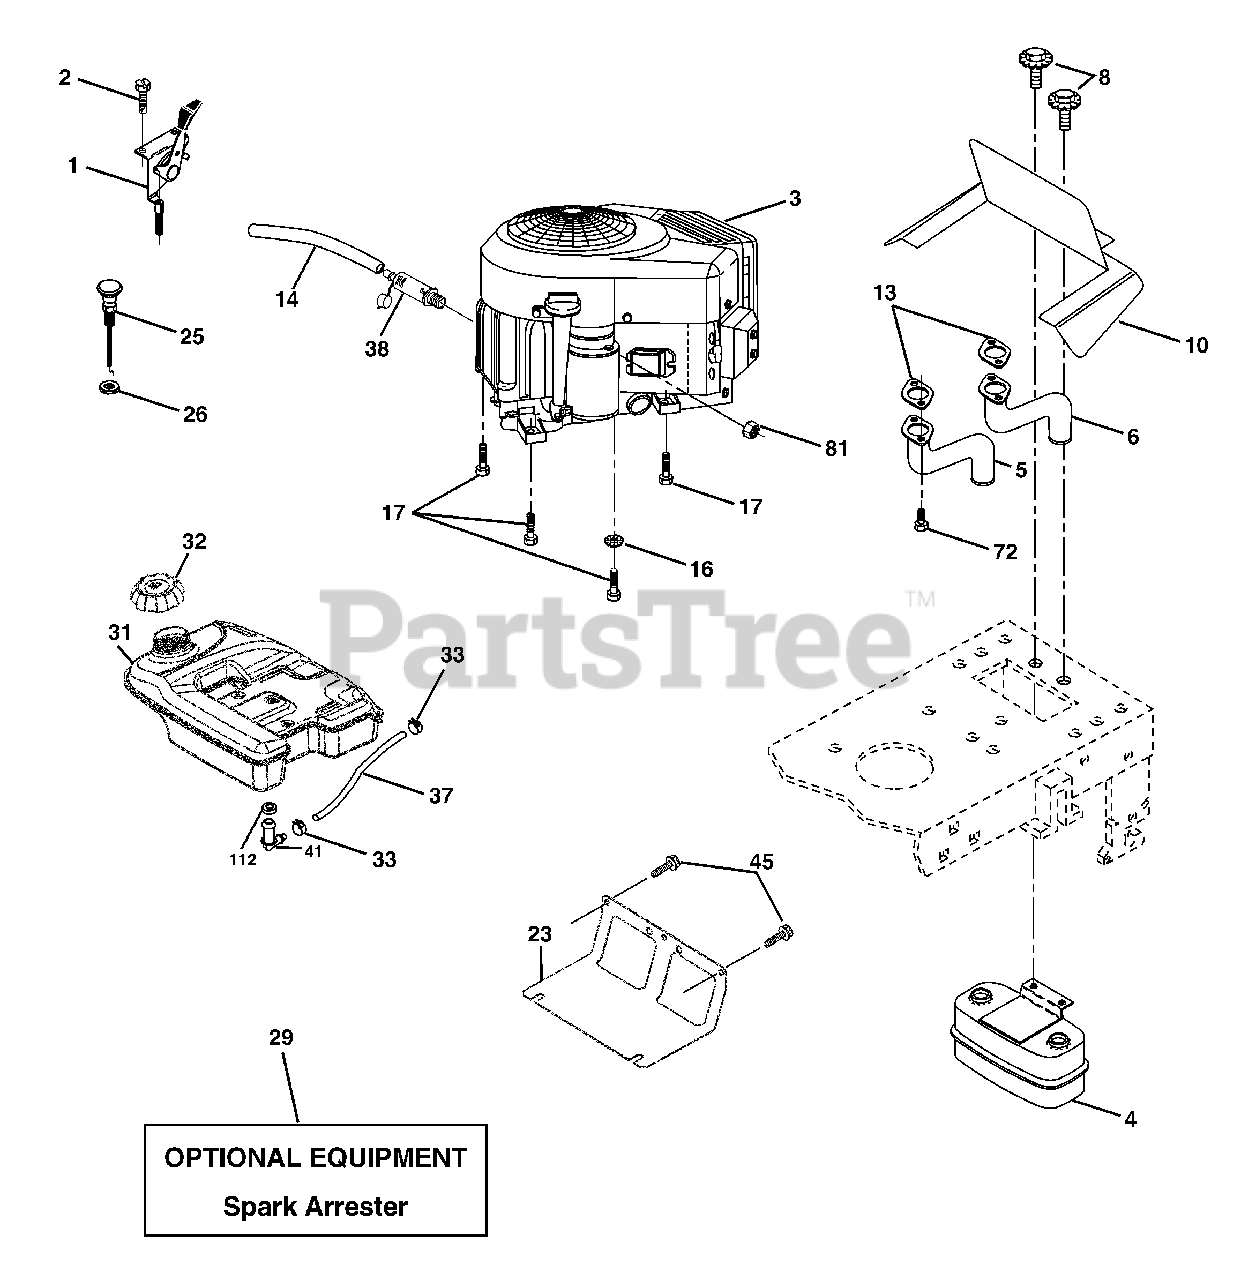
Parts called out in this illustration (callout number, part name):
1	Control Throttle
2	Screw Hw Hd Hi-Lo #13-16 x 3/4
4	Muffler Asm Twin Lo-Tone
5	Pipe Exhaust LH Intek
6	Pipe Exhaust RH Intek
8	Bolt 5/16-18 UNC x 3/4 w/Sems
10	Shield Browning Intek II
13	Muffler Gasket
14	Tube Drain Oil Easy
16	Washer Lock Ext Tooth 3/8
17	Screw Thdrol 3/8-16 x 1-1/2
23	Shield Heat
25	Choke Control
26	Nut, Keps 3/8-24 UNF
29	Kit Spark Arrestor (Flat Scrn)
31	Tank Fuel 4.0 Rear
32	Cap Asm Fuel
33	Clamp Hose Black
34	Pad, Spacer
37	Line Fuel
38	Plug Drain Oil
41	Stem Tank Fuel
45	Screw Hexwsh Thdr 3/8-16 x 3/4
72	Screw Socket Head 5/16-18 x 1
81	Nut Keps Hex 1/4-20 Unc
112	Bushing
